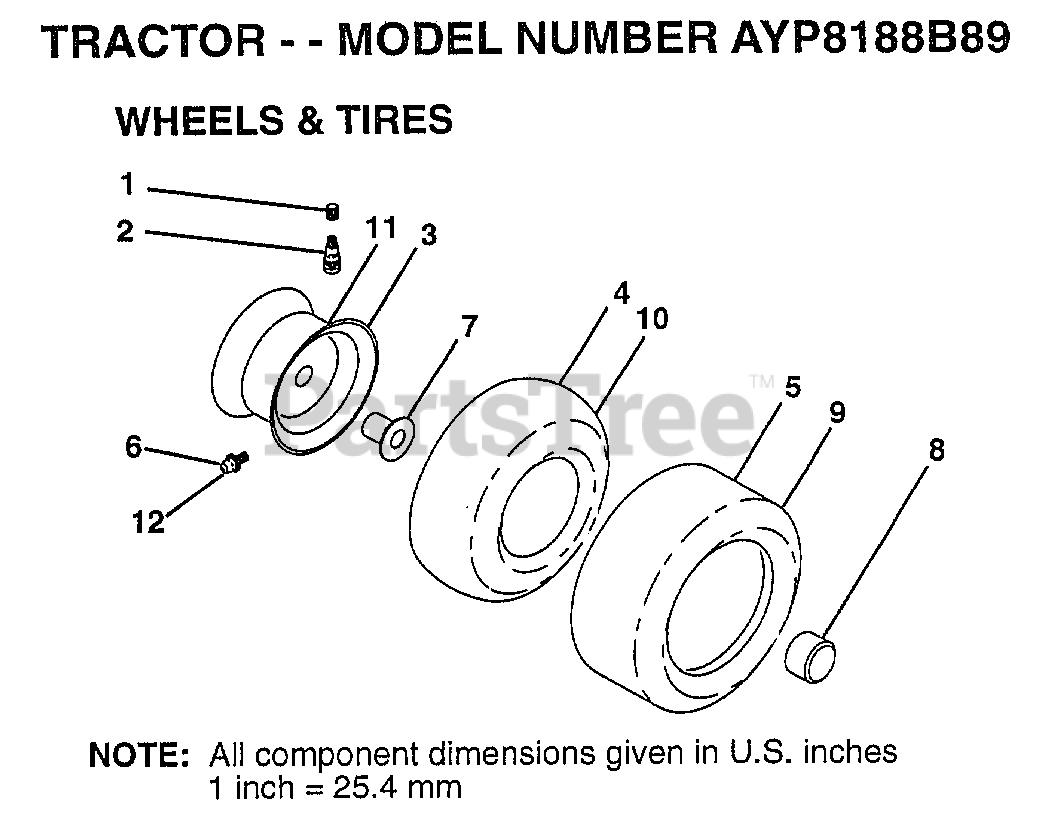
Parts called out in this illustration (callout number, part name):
1	VALVE CAP
2	VALVE STEM LT
3	"RIM ASM 8"" FRT"
4	TUBE.16X6.5/7.5-8
6	FITTING LT
7	"FLANGE, BEARING"
8	HUB CAP
10	TUBE.23X8/10-12
11	"RIM ASM 12"" REAR"
12	ZERK FITTING M
